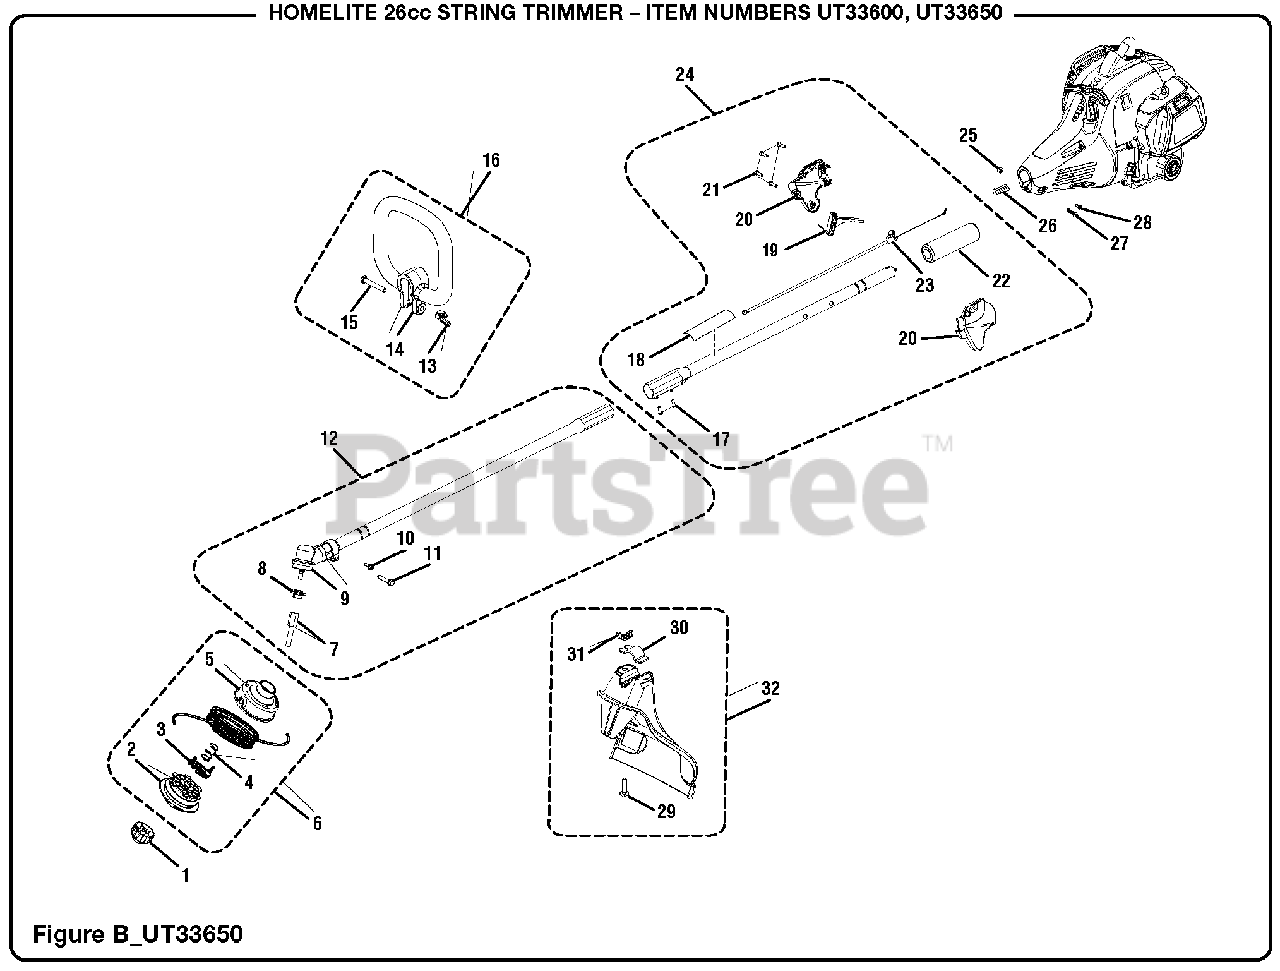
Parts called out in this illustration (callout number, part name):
1	Spool Retainer
3	Spool Cover
4	Compression Spring
5	String Head Housing
6	String Head Assembly
7	Adaptor
8	Flange Washer
9	Gear Head
10	Screw w/Washer (10-24 x 5/8 in., Hex Hd. T.F.)
11	Screw (1/4-20 x 1-1/4 in., Hex Hd.)
12	Lower Boom Assembly
13	Wing Nut (1/4-20, Plastic)
14	Front Handle
15	Bolt (1/4-20 x 45 mm, Cap Hex Hd.)
16	Front Handle Assembly
17	Set Screw (M5 x 10 mm, Hex Soc. Hd.)
18	Icon Warning Label
19	Throttle Trigger
20	Handle Assembly
21	Screw (M4 x 20 mm, T20 Torx Pan Hd. T.Fl.)
22	Foam Grip
23	Throttle Cable
24	Boom Assembly
25	Hex Nut (M6)
26	Compression Spring
27	Screw (M6 x 20 mm, T27 Torx Button Hd.)
28	Screw (M4 x 8 mm, T20 Torx Round Hd.)
29	Bolt (1/4-20 x 1 in., Square Hd.)
31	Wing Nut (1/4-20)
32	Grass Deflector Assembly
